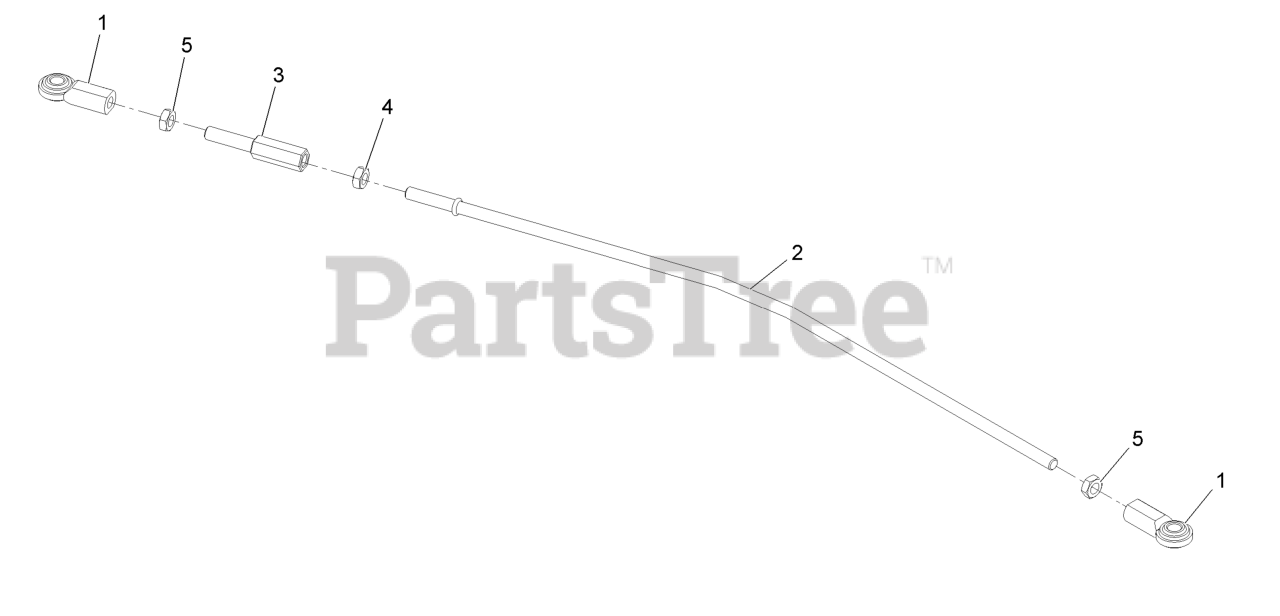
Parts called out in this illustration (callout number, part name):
1	Balljoint
2	Link-Lower, Motion Control
3	Rod-Adjustment
4	Nut-Jam 3/8-24 LH
5	Nut-Jam 3/8-24
